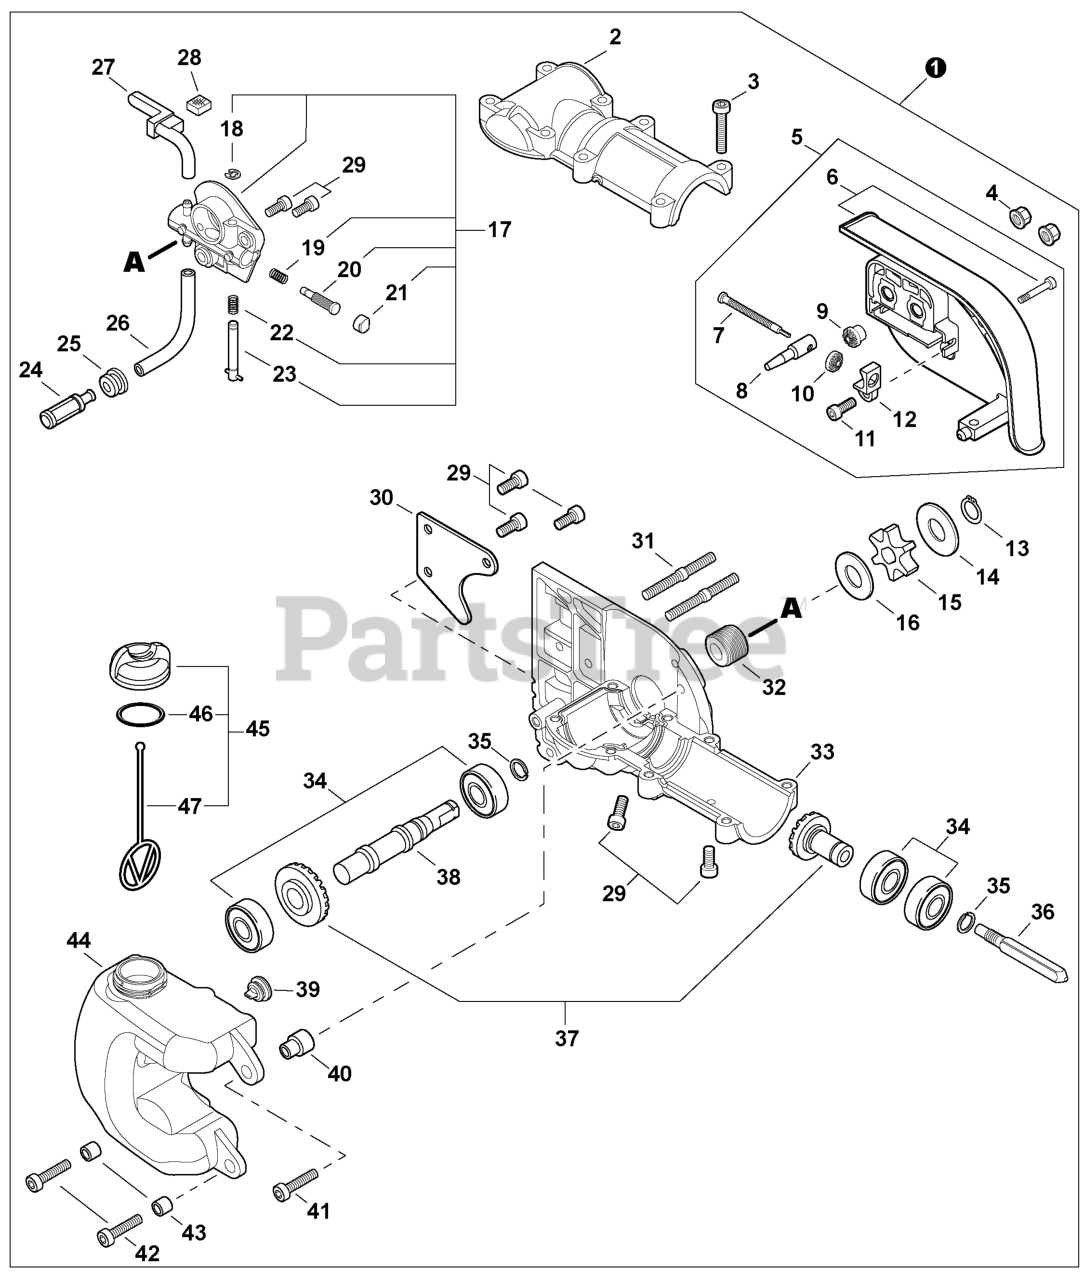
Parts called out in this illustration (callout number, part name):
1	GEAR CASE ASSY
2	COVER, GEAR CASE
3	BOLT, TORX 5x25
4	NUT, FLANGE M6
5	SPROCKET GUARD ASSY
6	GUARD, SPROCKET
8	TENSIONER, CHAIN
9	GEAR - 14 TOOTH
10	GEAR - 14 TOOTH
11	SCREW 4
12	COLLAR 8
13	RING, SNAP
14	WASHER 10
15	SPROCKET, DRIVE
16	WASHER 10
17	AUTO-OILER ASSY
20	PLUNGER ASSY
21	CAP, PLUNGER
23	ADJUSTER, OILER
24	FILTER, OIL
26	PIPE 3x6x70
27	PIPE, OIL OUTLET
28	PAD, FOAM
29	BOLT, TORX 5x10
31	BOLT, STUD 6
32	GEAR, WORM
33	CASE, GEAR
34	BEARING, BALL
35	RING, SNAP 12
36	CONNECTOR, DRIVESHAFT
37	GEAR SET, BEVEL
38	SHAFT, GEAR
39	VENT ASSY
40	COLLAR 6
41	BOLT, TORX 5x25
42	BOLT, TORX 5x20
43	SPACER 6.2x7.8x6
44	TANK, OIL
45	CAP ASSY
46	O-RING 18
47	CONNECTOR, CAP L= 60 MM
